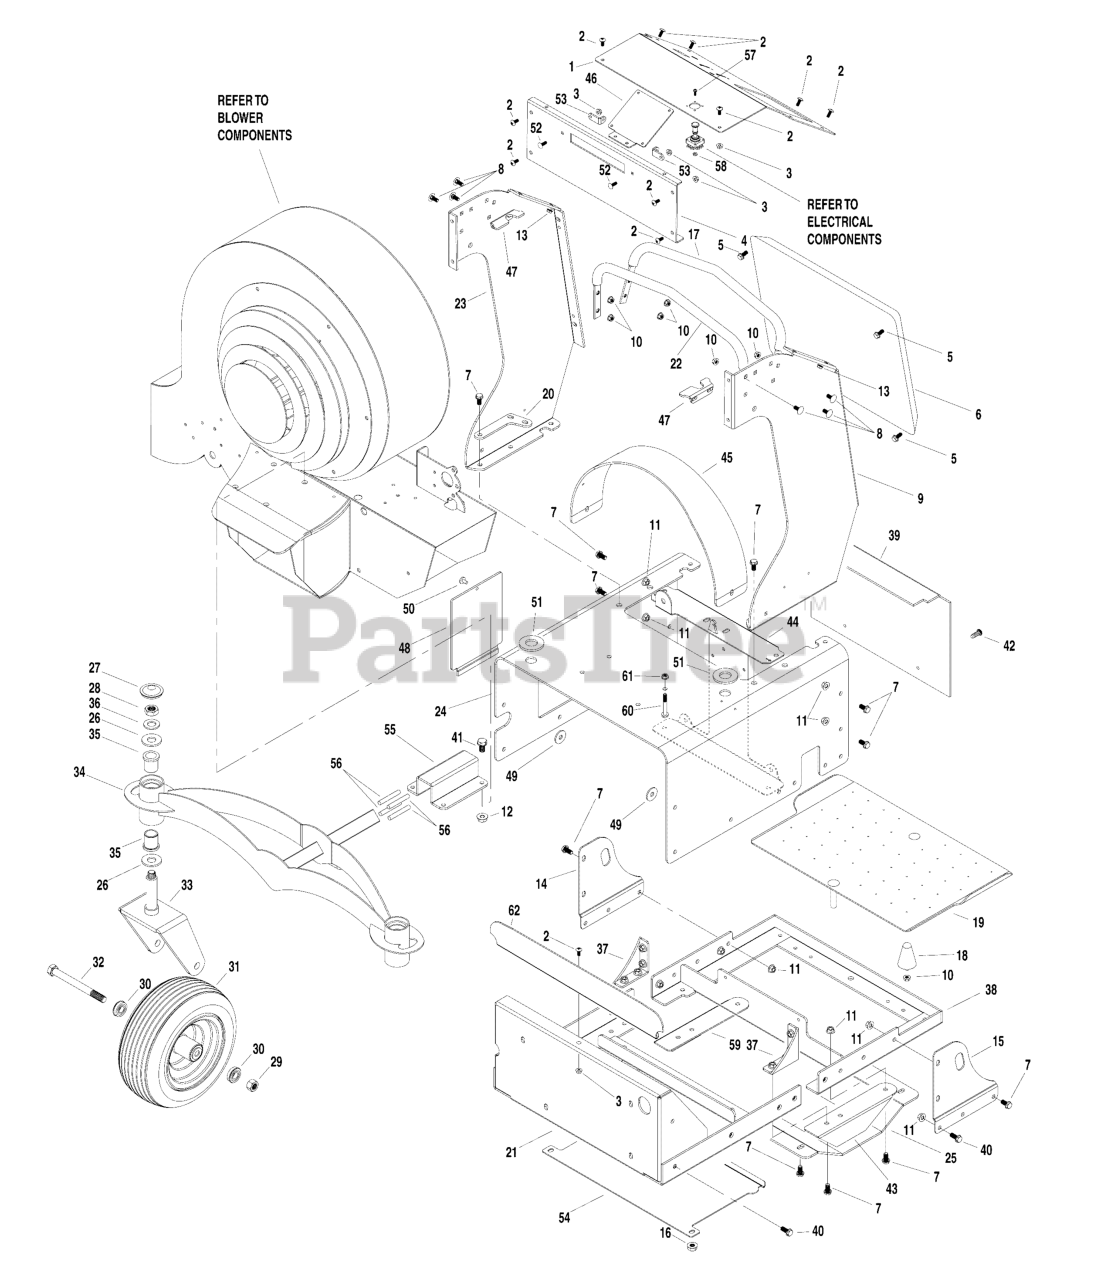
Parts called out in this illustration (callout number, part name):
1	PLATE, DASH PANEL, X3,Z3 (ZF17452)
2	BOLT, 1/4-20 X 3/4, FLANGE, CZ
3	NUT, 1/4-20 HEX SERR. FLANGE
4	WELD, DASH FRONT PANEL (ZFT17451)
5	BOLT, 5/16-18 X 3/4, FLANGE, CZ
6	KNEE PAD, BLWR
7	BOLT, 3/8-16 X 3/4, FLANGE, CZ
8	BOLT, 5/16-18 X 3/4, CARRIAGE, GD5, CZ
9	CONTROL TOWER Z3, LH - RED
10	NUT, 5/16-18 HEX SERRATED FLANGE (SMALL)
11	NUT, 3/8-16 Hex Large Serrated Flange
12	NUT, 1/2-13 SERRATED FLANGE, CZ
13	NUT, 1/4-20, RIV, CZ
14	PLATE, TIE DOWN RH (X310-T2006)
15	PLATE TIE DOWN LH - RED
16	NUT, 3/8-16 Hex Large Serrated Flange
17	REAR HANDLE, BLWR - RED
18	BUMPER, RUBBER, 5/16-18
19	WELD, FOOT PLATE (X310-2011)
20	PLATE, UPPER BEAM MOUNT, Z3 - BLK
21	WELD, Z3 FRONT CHASSIS - BLK
22	FRONT HANDLE, BLWR - RED
23	CONTROL TOWER Z3, RH - RED
24	WELD, MOTOR BOX, Z3 - RED
25	PLATE, SKID - BLK
26	BUSHING, 1 X 10GA, MACHINED, YZ
27	CAP, GREASE, PLASTIC
28	NUT, 3/4-10, NYLOCK JAM, CZ
29	NUT, 5/8-11 HEX NYLOCK FLANGE
30	BEARING, CASTER
31	TIRE ASSEMBLY, 13 X 6.50 - 6
32	BOLT, 5/8-11 X 8-1/2, CZ
33	WELD, CASTER YOKE, Z3 BLOWER - RED
34	WELD, FRONT END FRAME, Z3000 - RED
35	BUSHING, FLANGE
36	BUSHING, 3/4, MACHINED (15137)
37	WELD, TRANS 90° MOUNT BRACKET (X3-14-3017)
38	WELD, Z3 REAR CHASSIS - BLK
39	PLATE, TOE KICK, FB3000 - RED
40	BOLT, 3/8-16 X 1, SER FLG GD5, CZ (15062)
41	BOLT, 1/2-13 X 1-1/4, FLANGE, CZ
42	SCREW, 5/16-18 X 1/2, SLF TPNG, CZ
43	BRACKET, BOTTOM CHASSIS RIGHT - BLK
44	WELD TRANS I-BEAM, Z3 (ZF15051)
45	PLATE, BELT GUARD COVER, Z3 - RED
46	BRACKET, RELAY MOUNT - BLK
47	BRACKET, NEUTRAL CENTERING, CZ
48	PLATE, BATTERY DOOR - RED
49	SPACER, MOTOR BOX 10GA
50	KNOB, 1/4-20 X 1/2 CAP SCREW
51	GROMMET, RUBBER
52	BOLT, 1/4-20 X 3/4, CARRIAGE, CZ (17109)
53	BRACKET, L HEADLIGHT MOUNT - BLK
54	GUARD, LOWER DEBRIS (ZF1445)
55	PLATE, BENT, FRONT END TORSION
56	CORD, RUBBER
57	SCREW, #8-32 X 3/8, ALLEN, SS
58	NUT, #8-32, KEPS, CZ
59	BRACKET, BOTTOM CHASSIS LEFT - BLK
60	BOLT, 5/16-18 X 2-1/4 SER FLNG GD5, CZ
61	NUT, 5/16-18 HEX SERRATED FLANGE (SMALL)
62	GUARD, FORWARD DEBRIS - BLK
